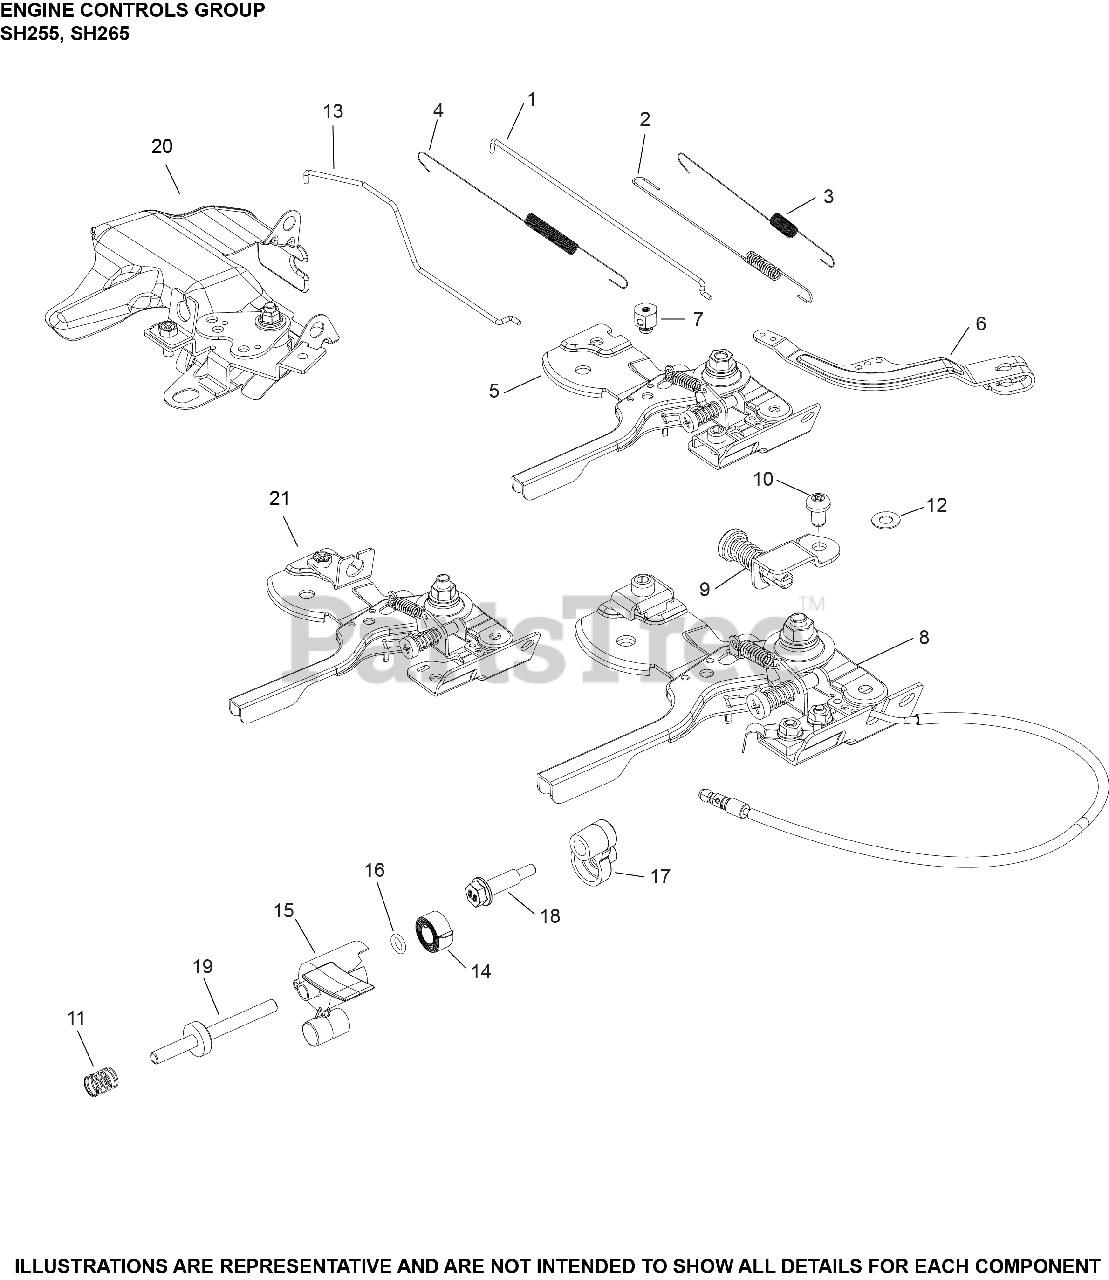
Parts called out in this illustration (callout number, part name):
1	LINKAGE, GOVERNOR - (#1807905S)
2	SPRING, GOVERNOR
4	SPRING, LINKAGE
5	SPEED CONTROL ASSEMBLY-FIXED
6	KIT, GOVERNOR LEVER
